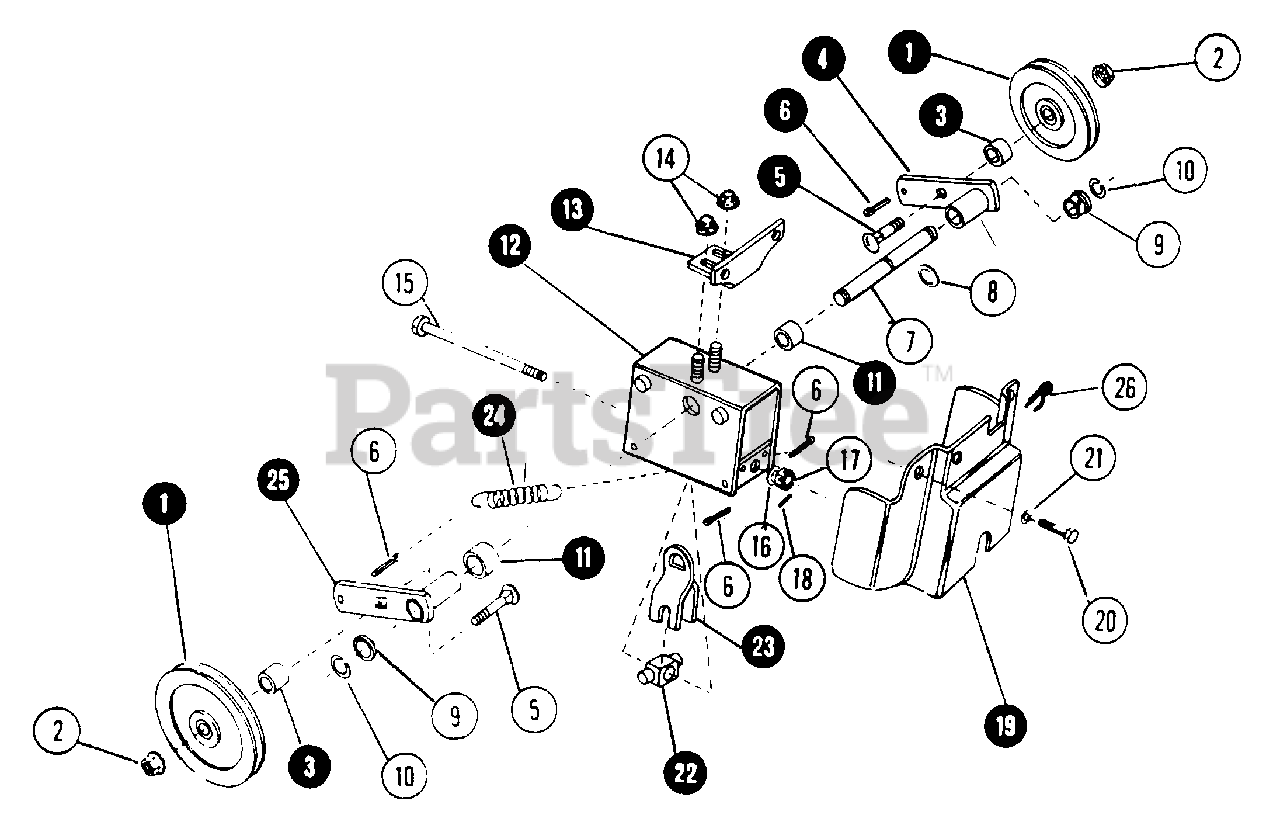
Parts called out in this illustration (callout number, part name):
1	PULLEY, IDLER
2	NUT, 1/2C FLANGE LOCK
3	SPACER, PULLEY
4	ARM, IDLER PULLEY LEFT SIDE
5	BOLT, 1/2C x 2 CARRIAGE
6	COTTER-PIN, 1/4 x 3/4
7	SHAFT, PULLEY RETAINER
8	WASHER, 17/32 x 7/8 x 5/64
9	SHIM, .009 - .011"
10	RING, SHAFT RETAINER
11	SPACER, IDLER ARM PULLEY
12	FRAME, IMPLEMENT DRIVE
13	BRACKET, MOUNTING
14	NUT, 3/8C FLANGE LOCK
15	BOLT, 3/8C HEX DRILLED
16	WASHER, 3/8" Flat
17	NUT, 3/8C HEX SLOTTED
18	PIN, SPIROL 3/32 x 9/16
19	COVER, IMPLEMENT DRIVE
20	BOLT, 5/16C x 7/8 HEX
21	WASHER, 5/16 FLAT
22	TRUNNION, PULLEY ADJUSTER
23	BRACKET, ADJUSTER
24	SPRING, IDLER PULLEY TENSION
25	ARM, IDLER PULLEY RIGHT SIDE
26	HAIR-PIN CLIP
